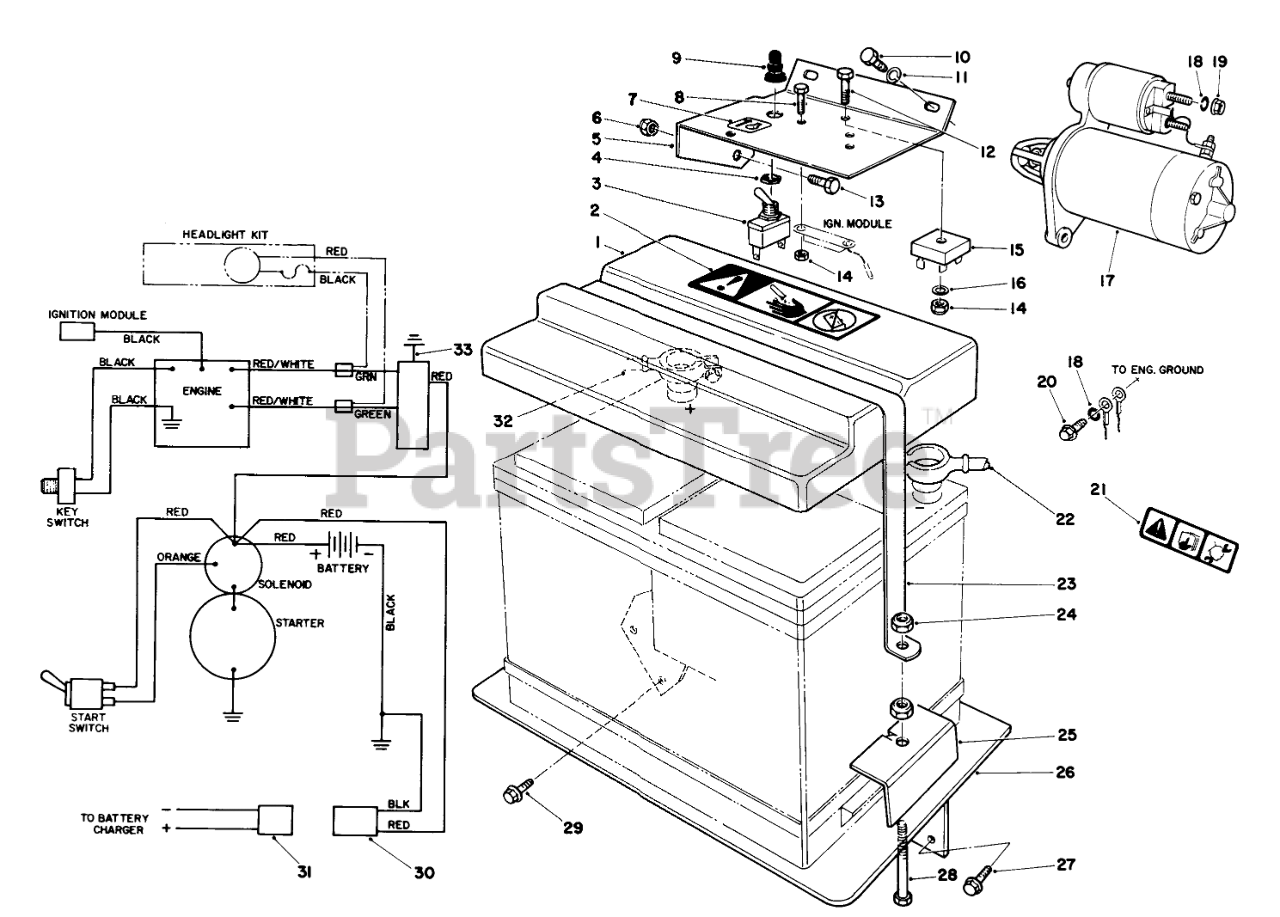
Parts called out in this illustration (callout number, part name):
1	BATTERY COVER
2	DECAL
3	Switch (Incl.Ref. #4 & 9)
4	NUT-LOCK
5	MOUNTING BRACKET
6	NUT-FLANGE, NI
7	DECAL - STARTER SWITCH
8	SCREW-SHH
9	BOOT-SWITCH
10	M6 X 1 HEX HD CAPSCRW
11	WASHER-SPRING
13	Screw-Cap Hex. Hd.
14	NUT-LOCK, NI
15	RECTIFIER-BRIDGE
16	WASHER-FLAT
17	12 Volt Starter Motor Assy.
18	WASHER-LOCK
19	NUT-FLANGE
20	SCREW-HHF
21	DECAL-WARNING
22	BATTERY CABLE
23	Strap Battery
24	NUT-LOCK, NI
25	BATTERY CLAMP
26	Plate-Battery
27	SCREW-HHF
28	SCREW-HH
29	SCREW-HHF
30	Charging Wire Assembly
31	FEMALE WIRE ASM
32	BATTERY CABLE
33	GROUND WIRE
